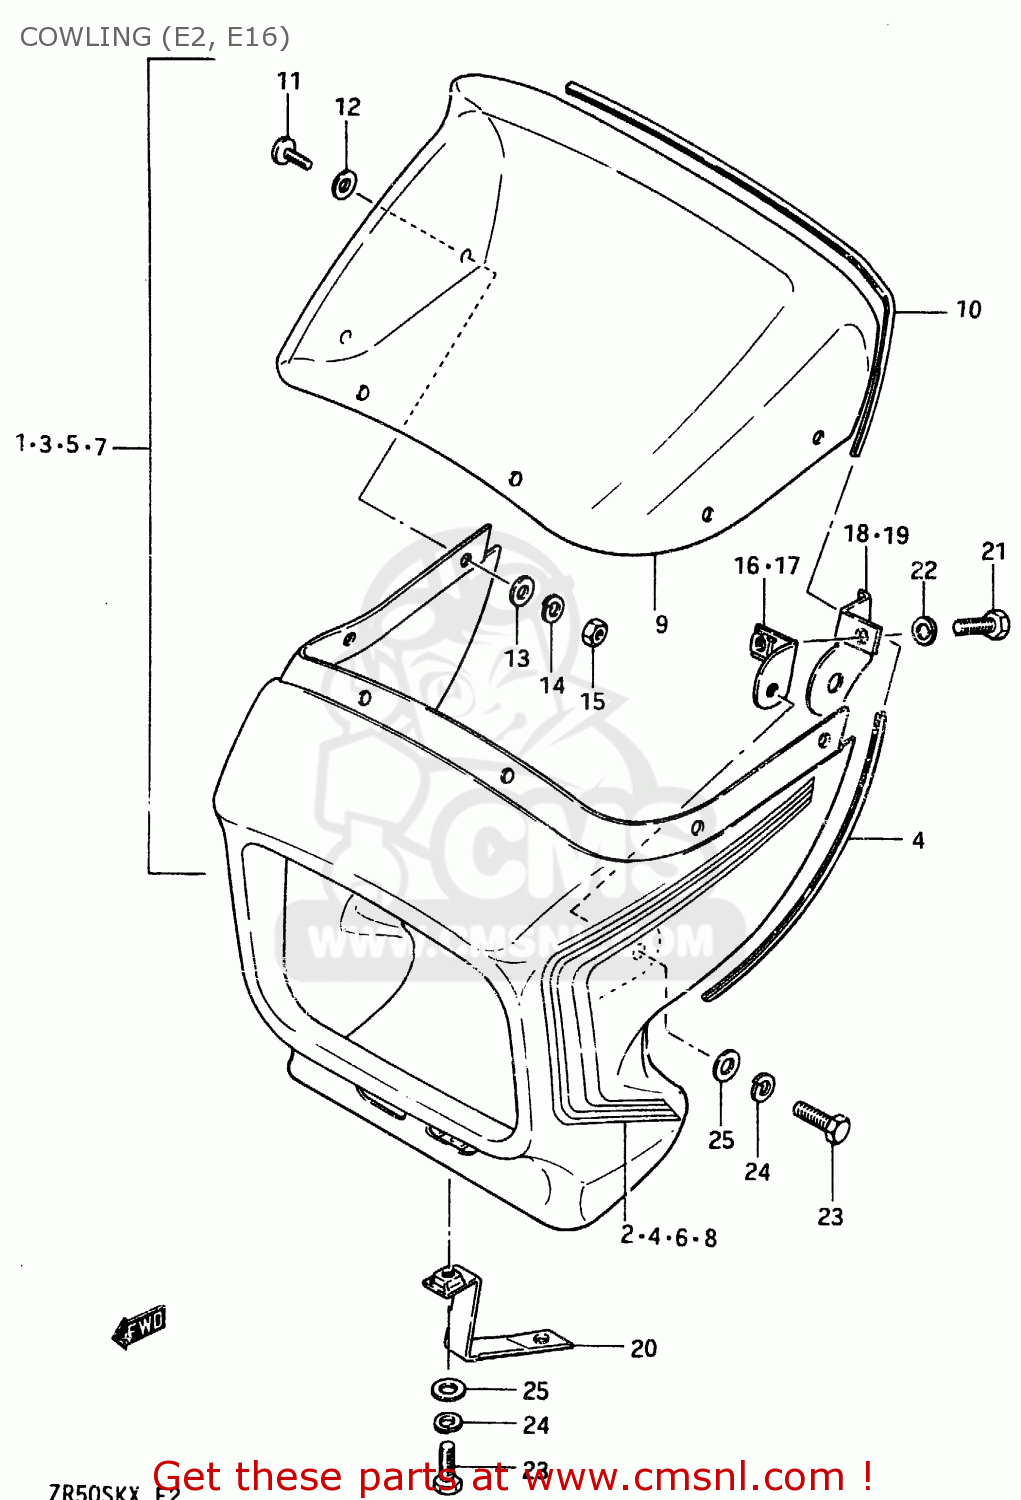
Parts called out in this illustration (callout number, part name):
1	COWLING ASSY
2	TAPE
3	COWLING ASSY
4	TAPE
5	COWLING ASSY
6	TAPE
7	COWLING ASSY
8	TAPE
9	WINDOW,COWLING
10	MOULDING, WINDOW
11	SCREW M5X12 DIN 7985/N
12	CUSHION
13	WASHER
14	LOCK WASHER
15	NUT
16	BRACE, RH (L:19)
17	BRACE,COWLING LH
18	BRACKET, FITTING RH
19	BRACKET, FITTING LH
20	BRACKET, LOWER
21	BOLT
22	LOCK WASHER
23	BOLT, UPPER
24	LOCK WASHER
25	WASHER (6.5X18X1.6)
